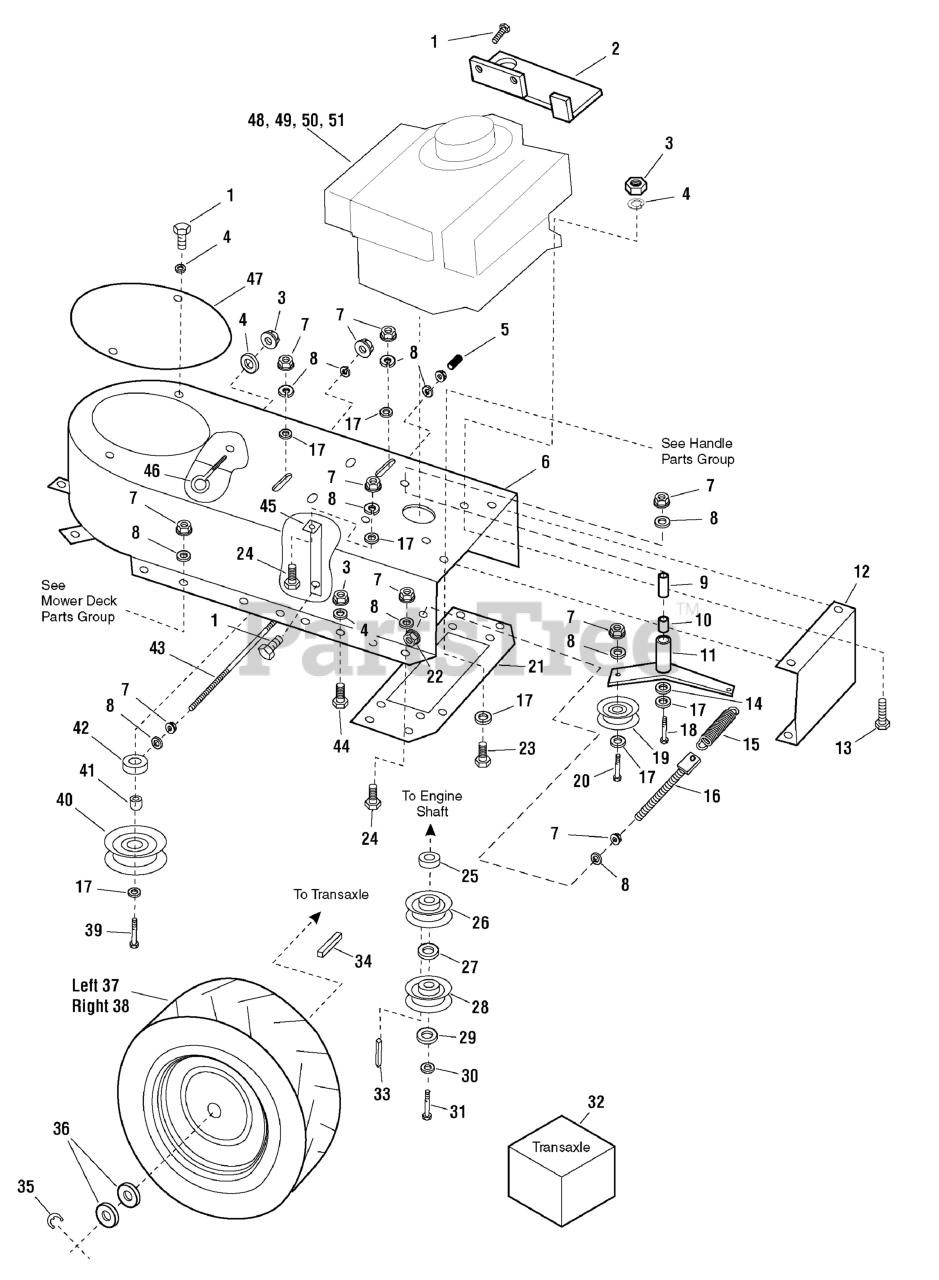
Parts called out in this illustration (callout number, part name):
1	BOLT, 5/16-18 x 3/4
2	Auxiliary fuel tank base
3	NUT, Hex, 5/16-18
4	Lockwasher, 5/16
5	Cap, Black
6	Engine Deck
7	NUT, Hex, 3/8-16
8	Lockwasher, 3/8
9	Idler Arm Pivot Boss
10	Sleeve Bushing, 3/4 ID
11	Transmission Idler Arm
12	Engine deck back cover
13	BOLT, 5/16-18 x 1-1/2
14	Flatwasher, 1/2
15	Idler Spring
16	Idler Tension Rod
17	Flatwasher, 3/8
18	CAPSCREW, 3/8-16 x 3-1/4
19	Idler Pulley
20	BOLT, 3/8-16 x 1-3/4
21	Lower handle mounting plate
22	NUT, Reverse Lock, 3/8-16
23	CAPSCREW, 3/8-16 x 1-1/4
24	BOLT, 3/8-16 x 1
25	Engine Shaft Spacer, 7/8"
26	Blade Clutch Drive Pulley
27	Spacer, 1/8"
28	Transmission Drive Pulley
29	Flatwasher Heavy Duty, 7/16
30	Lockwasher, 7/16
31	CAPSCREW, Socket Head, 7/16-20 x 1-1/2
32	Transaxle
33	Key, Engine Shaft, 1/4 x 1/4 x 2-1/8
34	Key, Axle Shaft 3/16 x 3/16 x 1-3/8
35	E clip
36	WASHER
37	Drive Wheel, Left
39	BOLT, 3/8-16 x 3-1/4
40	Blade clutch idler pulley
41	Idler pulley spacer bushing
42	Blade Clutch Idler Boss
43	Blade Clutch Idler Tensioning Rod
44	CAPSCREW, 5/16-18 x 2-1/4
45	Transmission Forward Mounting Hanger
46	EYE BOLT, 5/16-18x3-1/4
47	Clutch Cover Plate
48	ENGINE, 13.5HP Briggs & Stratton
49	ENGINE, 13HP Honda
50	ENGINE, 15HP Kawasaki
51	ENGINE, 16HP Briggs & Stratton
